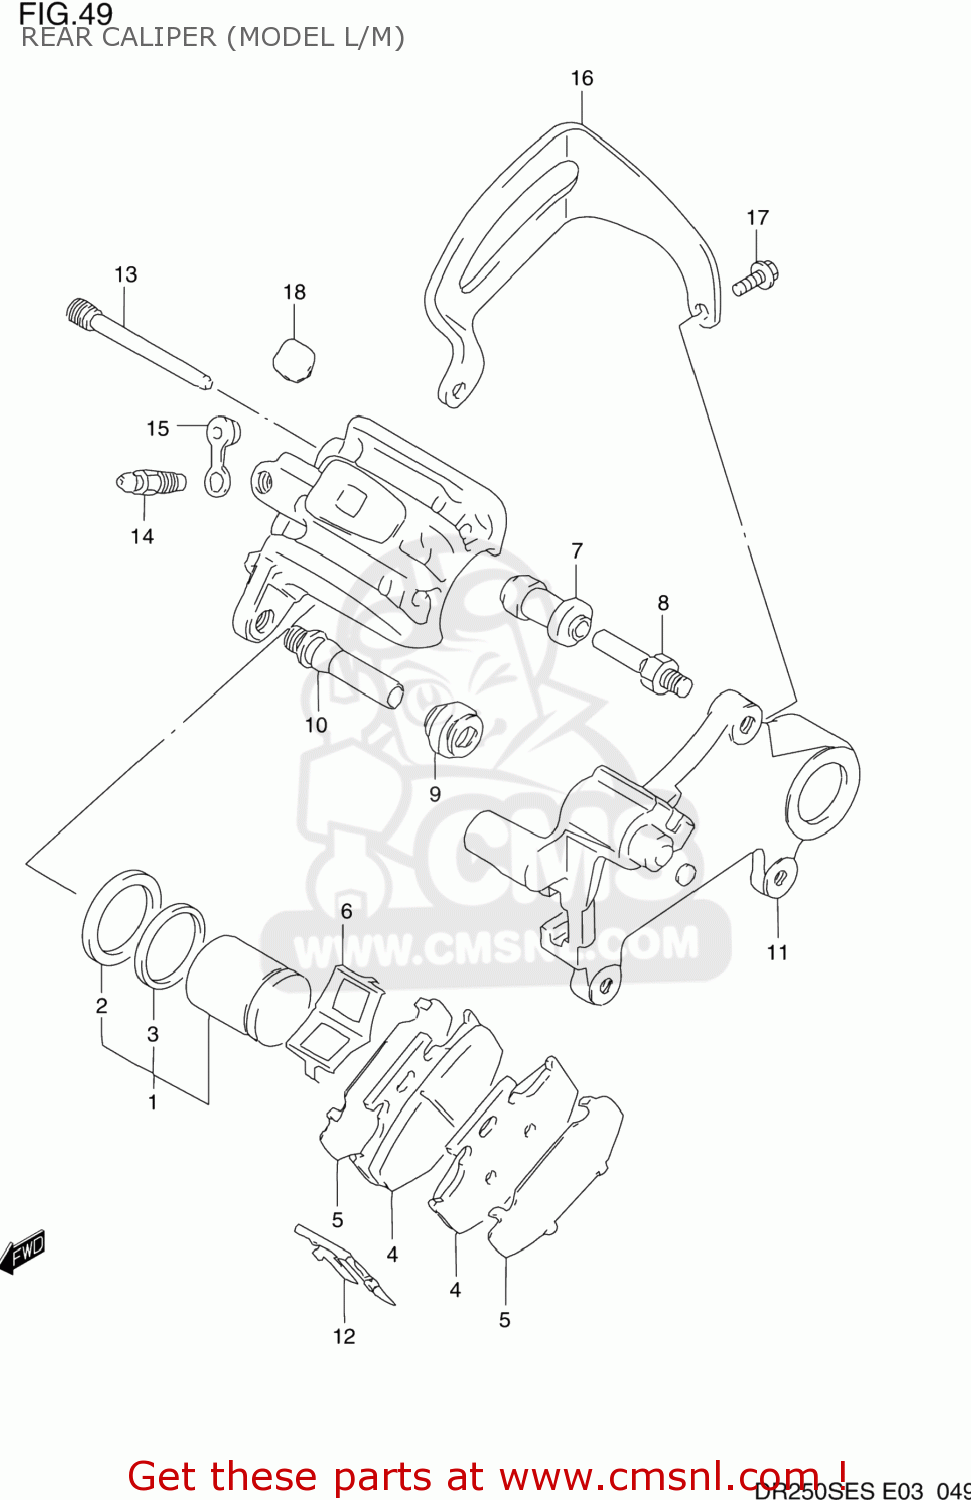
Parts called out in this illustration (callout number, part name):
1	PISTON SET
2	SEAL,PISTON
3	SEAL
4	PAD (MCA)
5	SHIM
6	SPRING,PAD
7	BOOT
8	PIN,BOLT
9	BOOT
10	PIN
11	BRACKET
12	RETAINER
13	PIN,HANGER
14	BLEEDER
15	CAP,BLEEDER
16	GUARD,RR CALIPER
17	BOLT
18	COVER,RR CALIPER BODY
